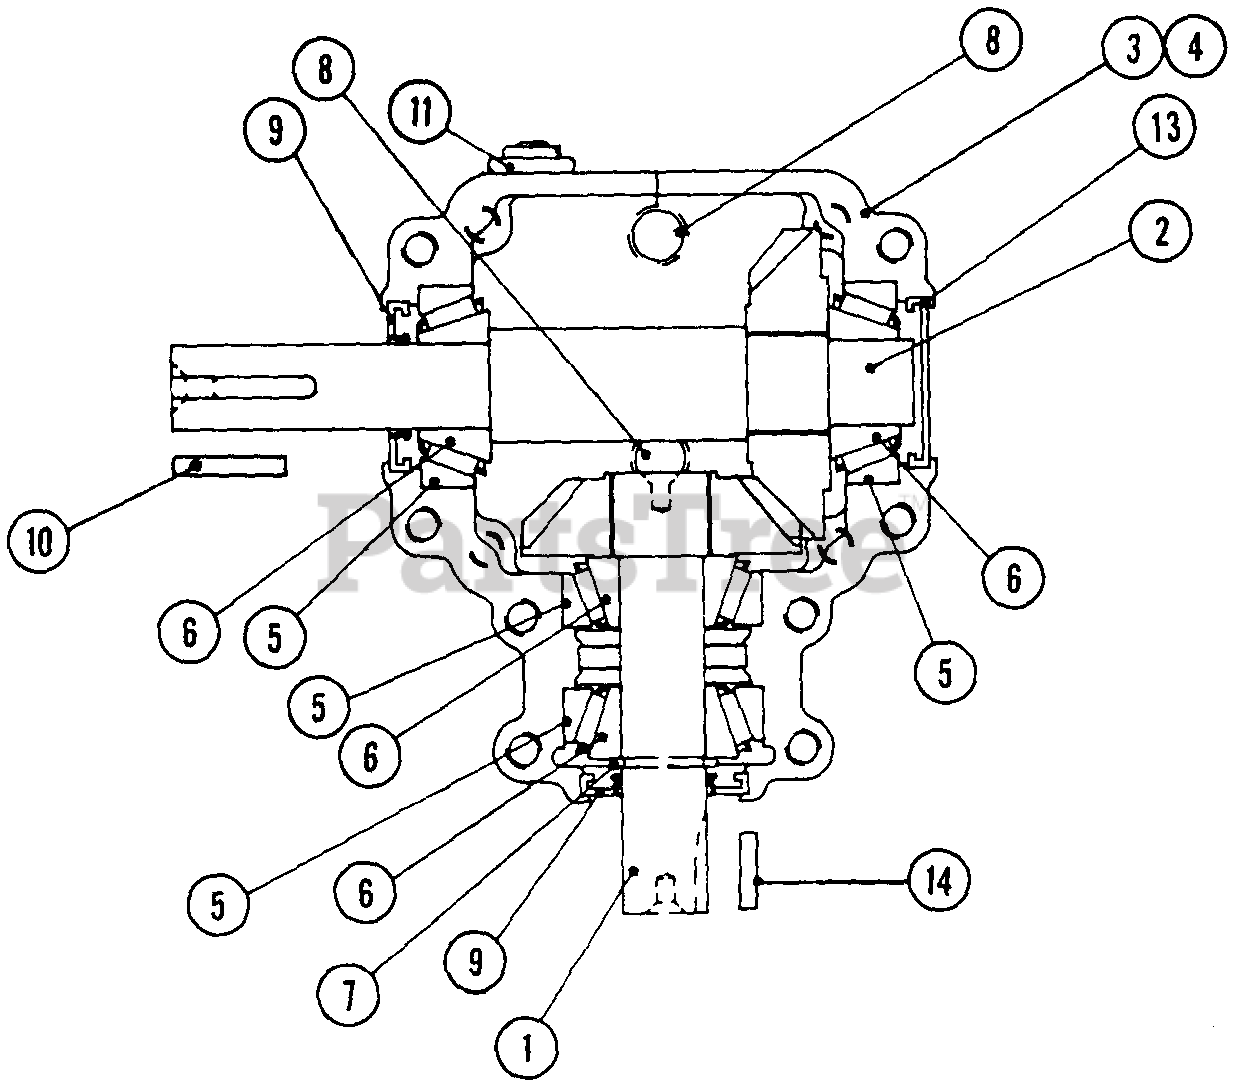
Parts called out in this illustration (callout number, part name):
1	SHAFT - pinion, with gear
2	SHAFT - cross, with gear
3	HOUSING - with tapped holes
5	CUP - bearing
6	CONE - bearing
7	RING - retaining
8	PLUG - pipe 1/4"
10	KEY - 3/16" x 1" input shaft
11	PIPE - vent
13	CAP - end
14	KEY - 3/16" x 5/8" output shaft
